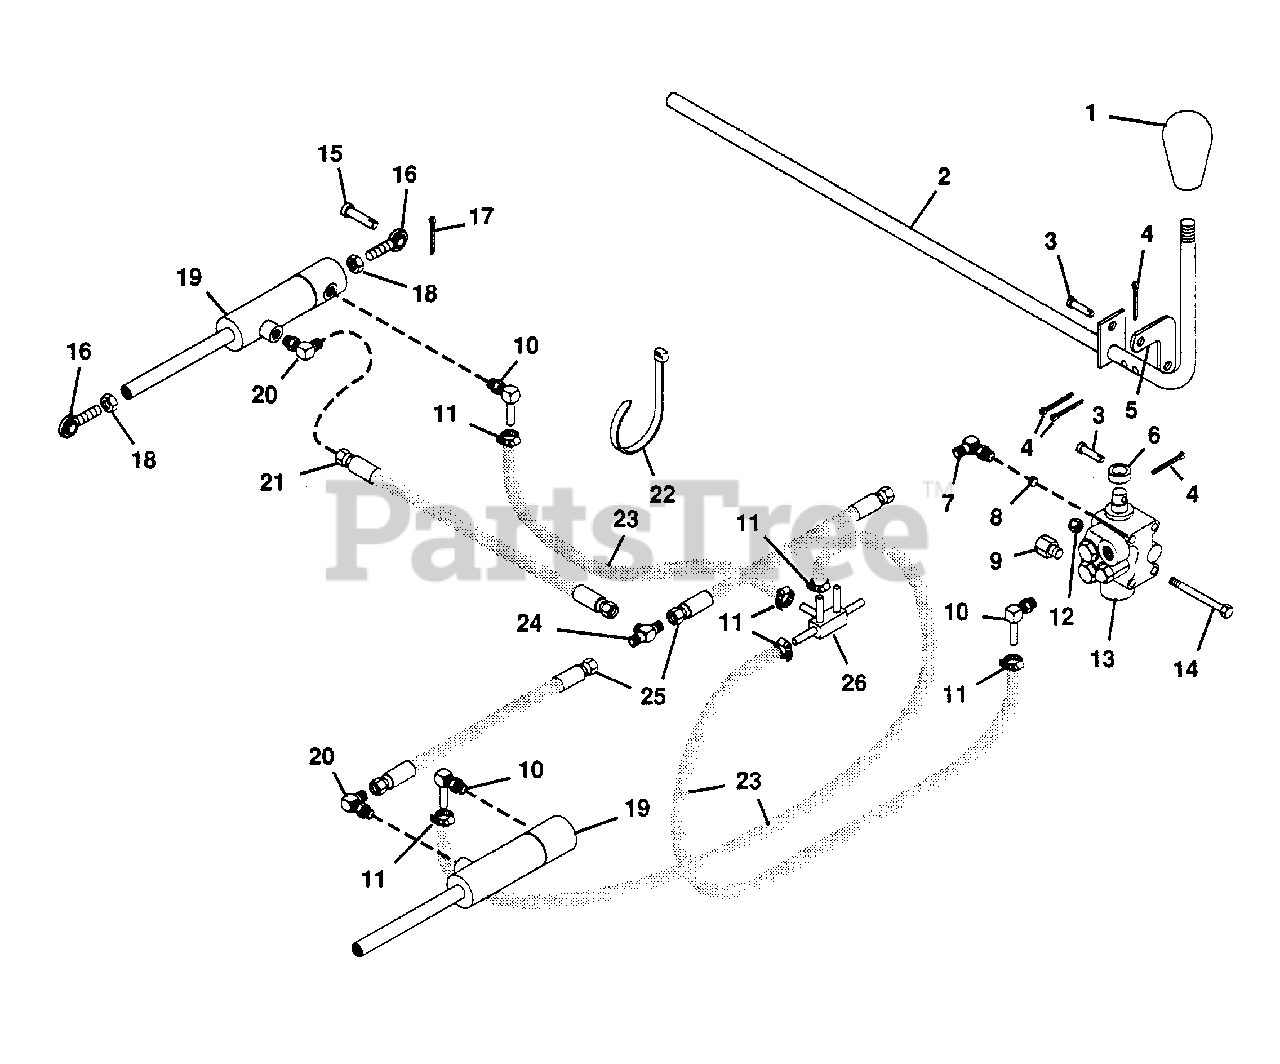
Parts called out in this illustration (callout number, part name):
1	Knob, PTO
2	Weldment, Lift Lever
3	Pin, Clevis
4	Pin, Cotter .094x.75
5	Rod, Hydraulic Control
6	Bush., St. .700x1.00x.300 Stl.
7	Adapter
8	Plate, Flow Restriction
9	Plug, PH 05PO-4
10	Adapter, 4601-6-6
11	Clamp, Hose
12	Nut, Lock 1/4-20
13	Valve, Hydraulic
14	Bolt, Hex 1/4-20x2.75
15	Pin, Clevis .50x1.330
16	Assembly, Rod End R.H.
17	Pin, Cotter .125x1.25
18	Nut, Jam 1/2-20
19	Cylinder, Steering
20	Adapter, PH 2503-6-6
21	Assembly, Hydraulic Hose
22	Tie Wrap, Black
23	Hose, Hydraulic
24	Adapter Tee
25	Assembly, Hydraulic Hose
26	Manifold
